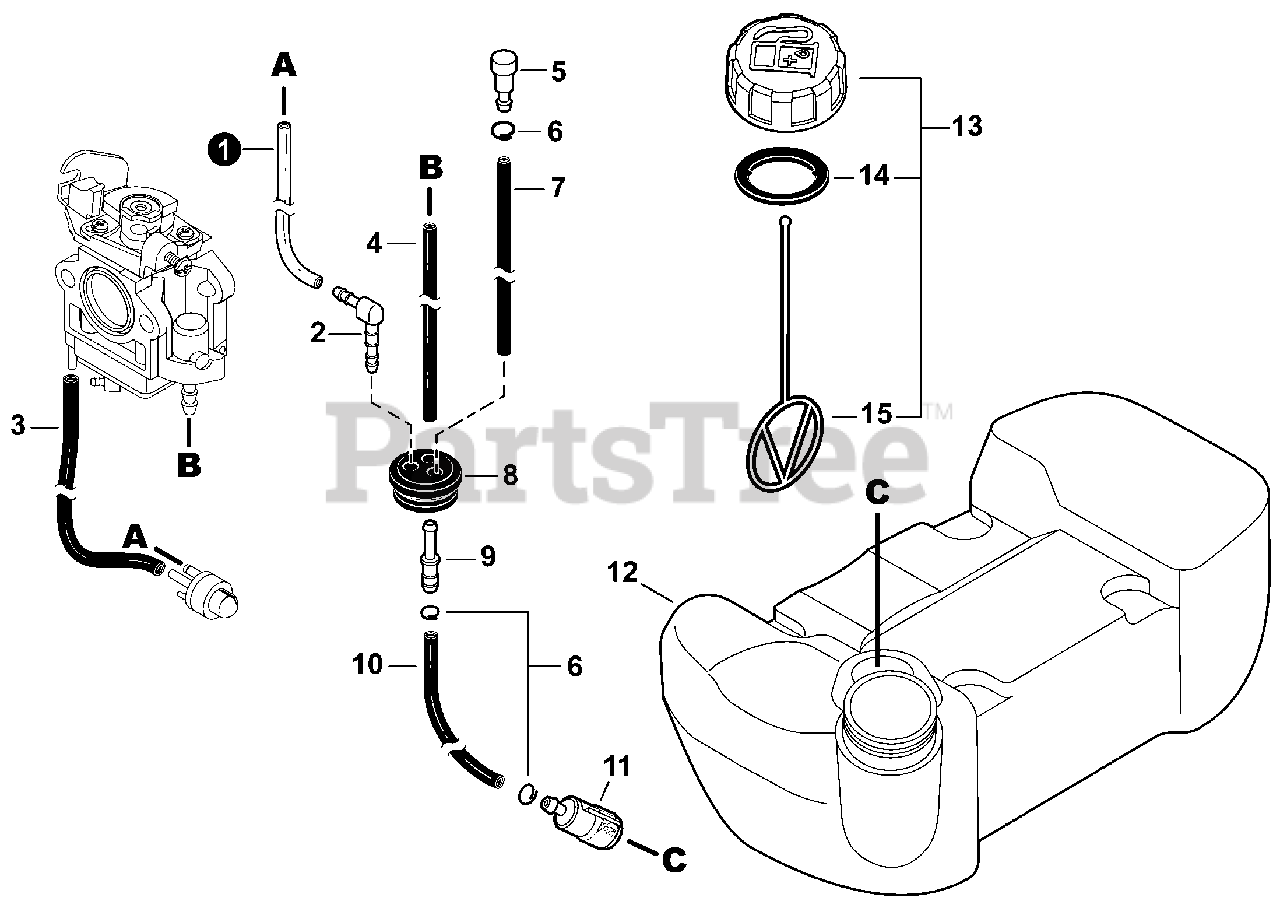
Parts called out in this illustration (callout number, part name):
1	PIPE, FUEL 3×6×60 CLEAR
2	CONNECTOR, PIPE
3	PIPE, FUEL 2.4×5×80 BLACK
4	PIPE, FUEL 3×5×55 BLACK
5	VENT ASSY
6	CLIP Ø6.5 MM
7	PIPE, FUEL 3×6×120 BLACK
8	GROMMET, FUEL
9	CONNECTOR, PIPE Ø5ר3.5
10	PIPE 3×6×125 BLACK
11	FILTER, FUEL
12	TANK, FUEL
13	CAP ASSY, FUEL
14	GASKET, FUEL CAP
15	CONNECTOR, CAP L= 100 MM
